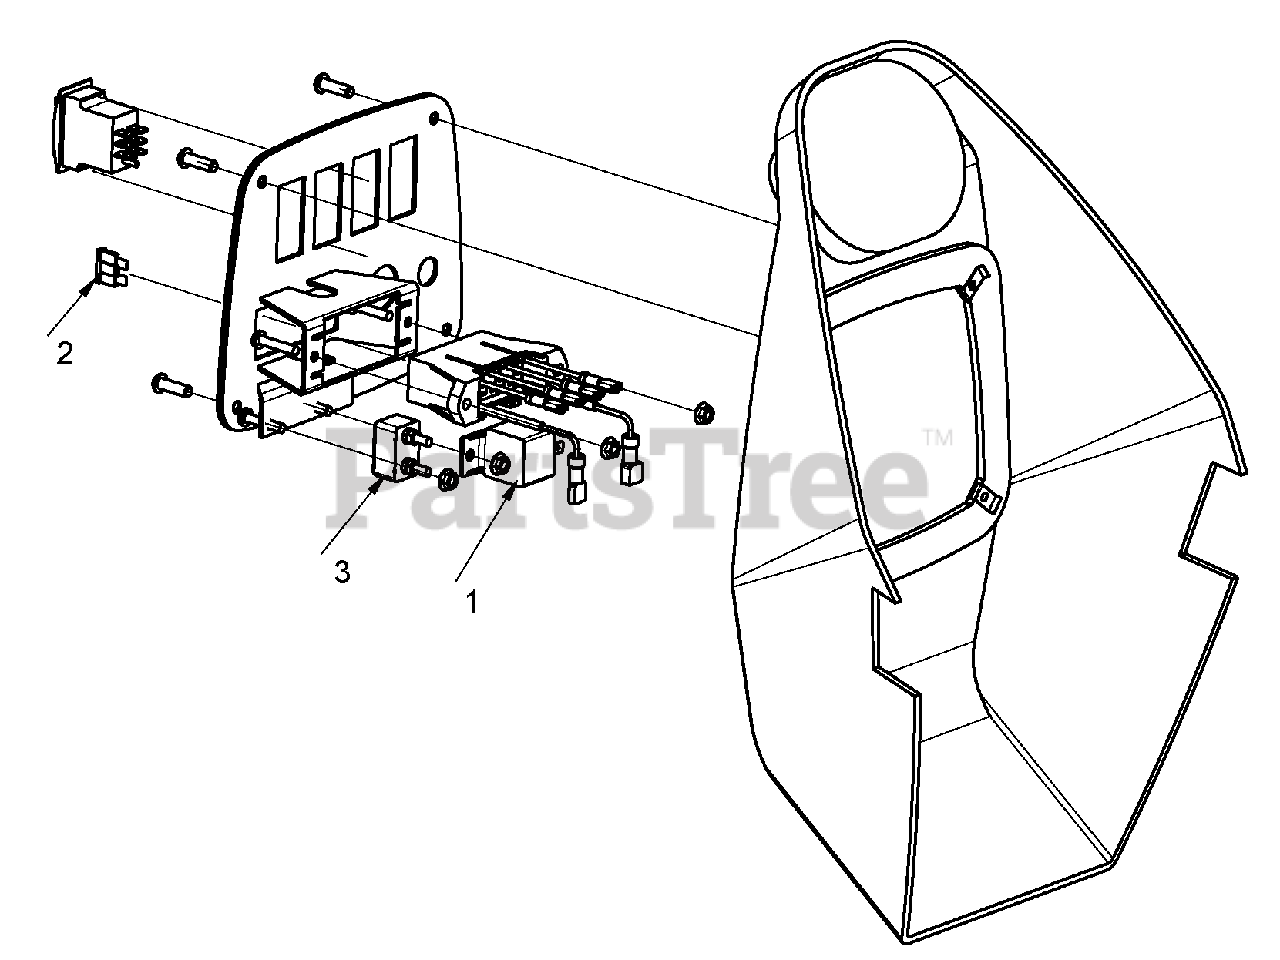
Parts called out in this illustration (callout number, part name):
1	Relay, Bosch
2	Fuse - Automotive Blade 20 AMP
3	Circuit Breaker, 40A Autoreset
